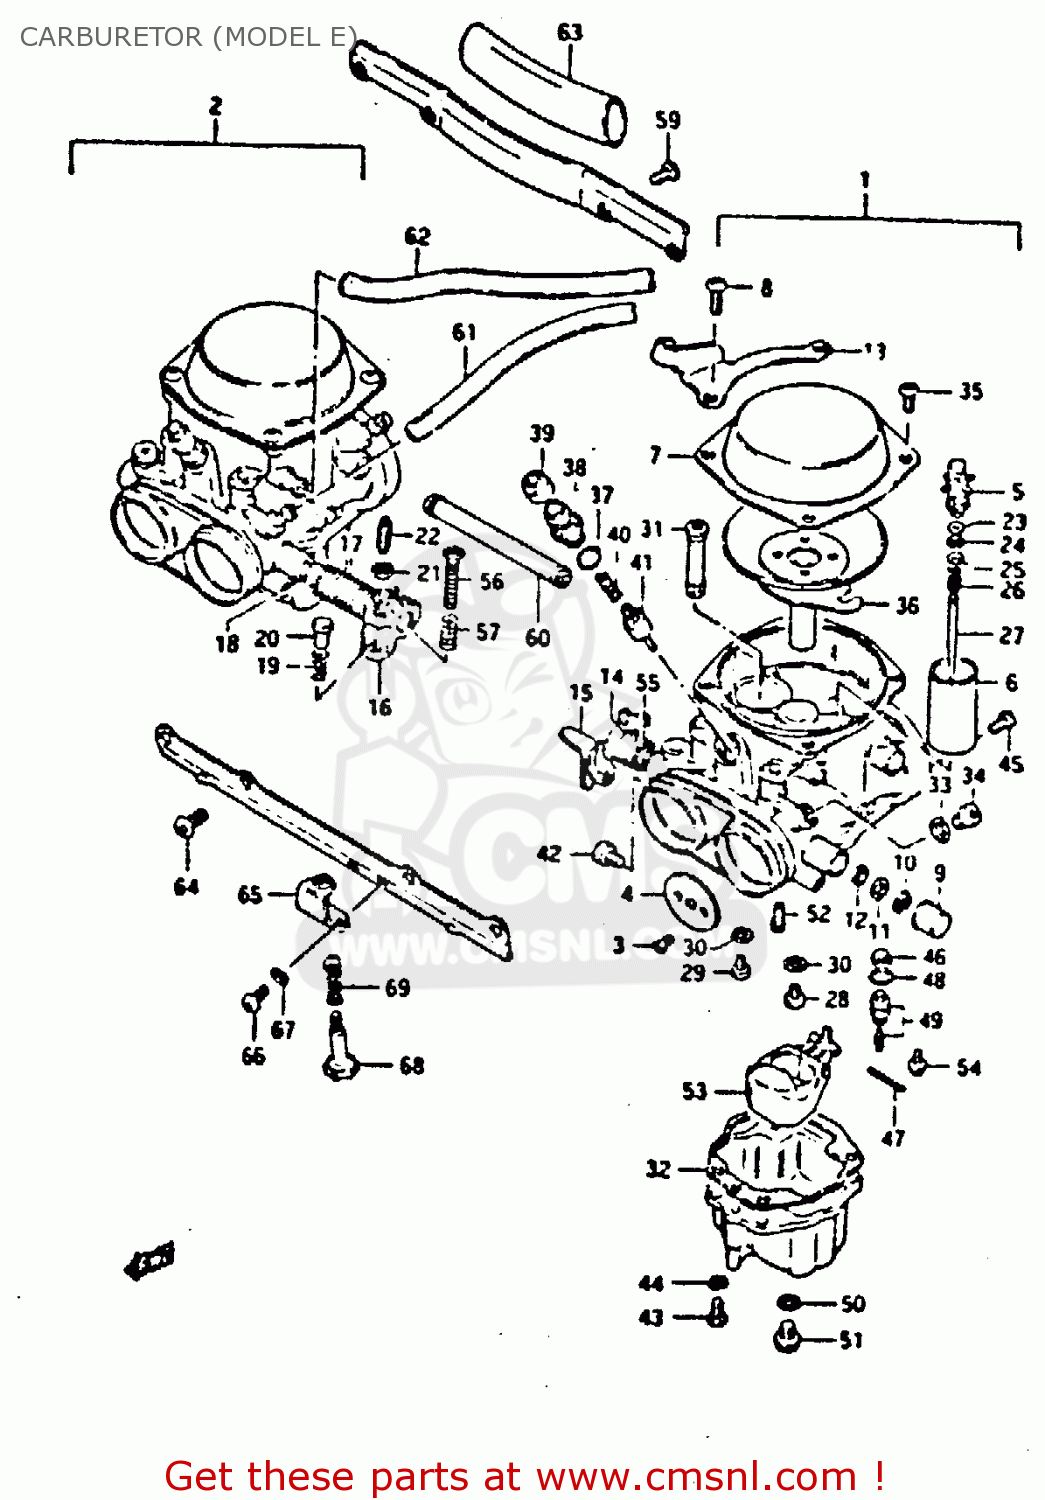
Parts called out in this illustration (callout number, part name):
1	CARBURETOR, LH
2	CARBURETOR, RH
3	SCREW
4	VALVE,THROTTLE
5	HOLDER,GUIDE
6	VALVE,THROTTLE
7	COVER,DIAPHRAGM
8	SCREW
9	CAP,THROTTLE SHAFT
10	E RING
11	GASKET,THROTTLE SHAFT (NAS)
12	SEAL
13	BRACKET,THROTTLE CABLE
14	SPRING,THROTTLE SHAFT
15	SHAFT ASSEMBLY
16	SHAFT ASSEMBLY
17	SPRING
18	RING
19	SPRING,THROTTLE SCREW
20	PIN,THROTTLE LEVER
21	NUT
22	SCREW
23	RING
24	CAP,LEVER
25	WASHER
26	SPRING
27	NEEDLE, JET (5C13-3)
28	JET,MAIN(90)
29	JET,MAIN(97.5)
30	WASHER,NEEDLE NOZZLE
31	JET, NEEDLE (P-4)
32	GASKET,FLOAT CHAMBER (MCA)
33	WASHER
34	SCREW
35	SCREW
36	DIAPHRAGM,CARBURETOR
37	O RING
38	HOLDER,GUIDE
39	CAP
40	SPRING
41	VALVE,STARTER
42	SCREW
43	SCREW
44	LOCK WASHER
45	JET, PILOT AIR (140)
46	FILTER
47	PIN,FLOAT
48	O-RING,NEEDLE VALVE
49	VALVE ASSEMBLY,NEEDLE
50	GASKET (NAS)
51	PLUG,DRAIN
52	JET,PILOT(37.5)
53	FLOAT
54	SCREW
55	RING,THROTTLE SHAFT
56	SCREW
57	SPRING
58	FLANGE ASSEMBLY,CARBURETOR
59	SCREW
60	PIPE,CARBURETOR
61	HOSE 4.5X8X390
62	HOSE
63	HOSE(16X19X100)
64	SCREW
65	BRACKET,SLOW ADJUST
66	SCREW
67	LOCK WASHER
68	ADJUSTER
69	SPRING
